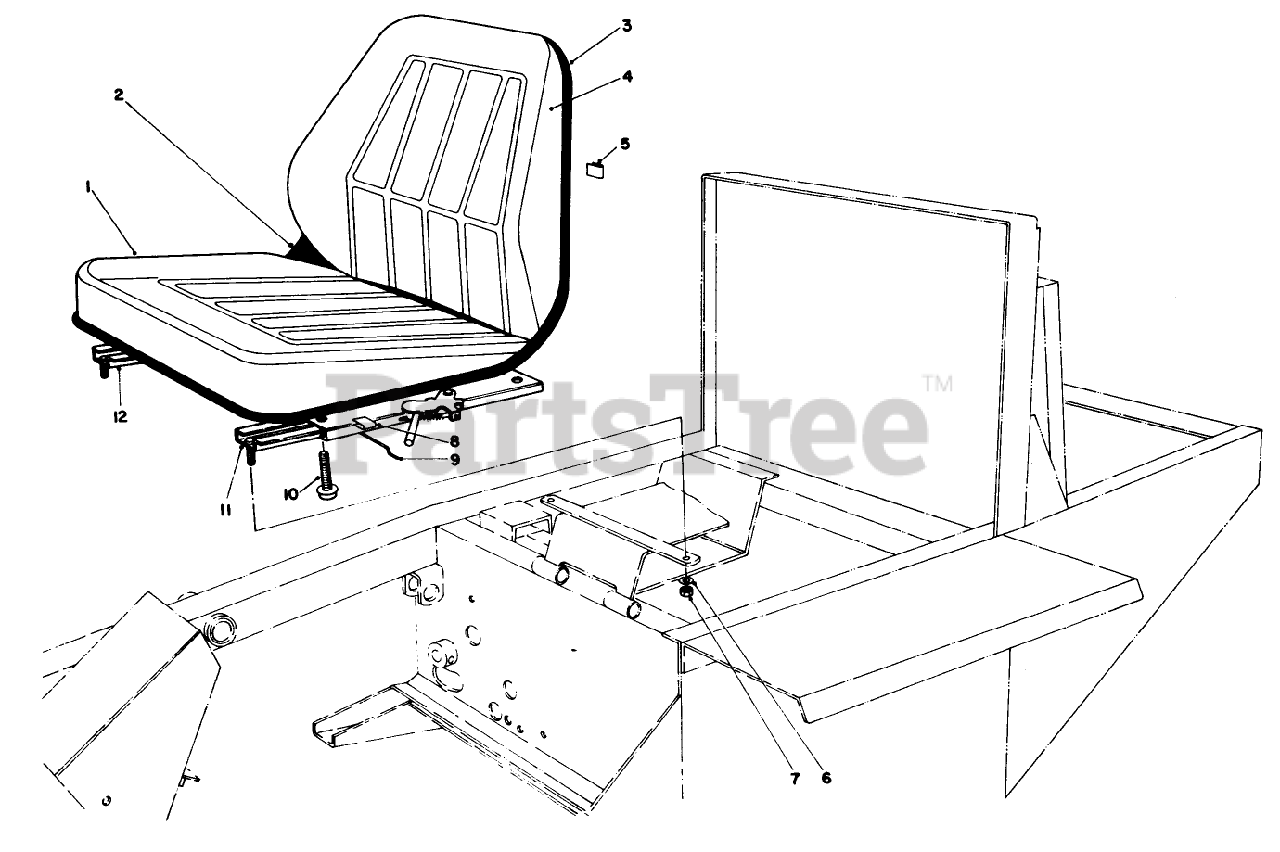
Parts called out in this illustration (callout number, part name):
1	Seat-Cushion (Incl. Ref. #5 & 8)
2	Shell
3	EDGING
4	Backrest (Incl. Ref. #5 & 8)
6	WASHER-LOCK
7	NUT-HEX
9	Connecting Rod
10	SCREW-HHF
11	ADJUSTER-SEAT, LH
12	ADJUSTER-SEAT, RH
